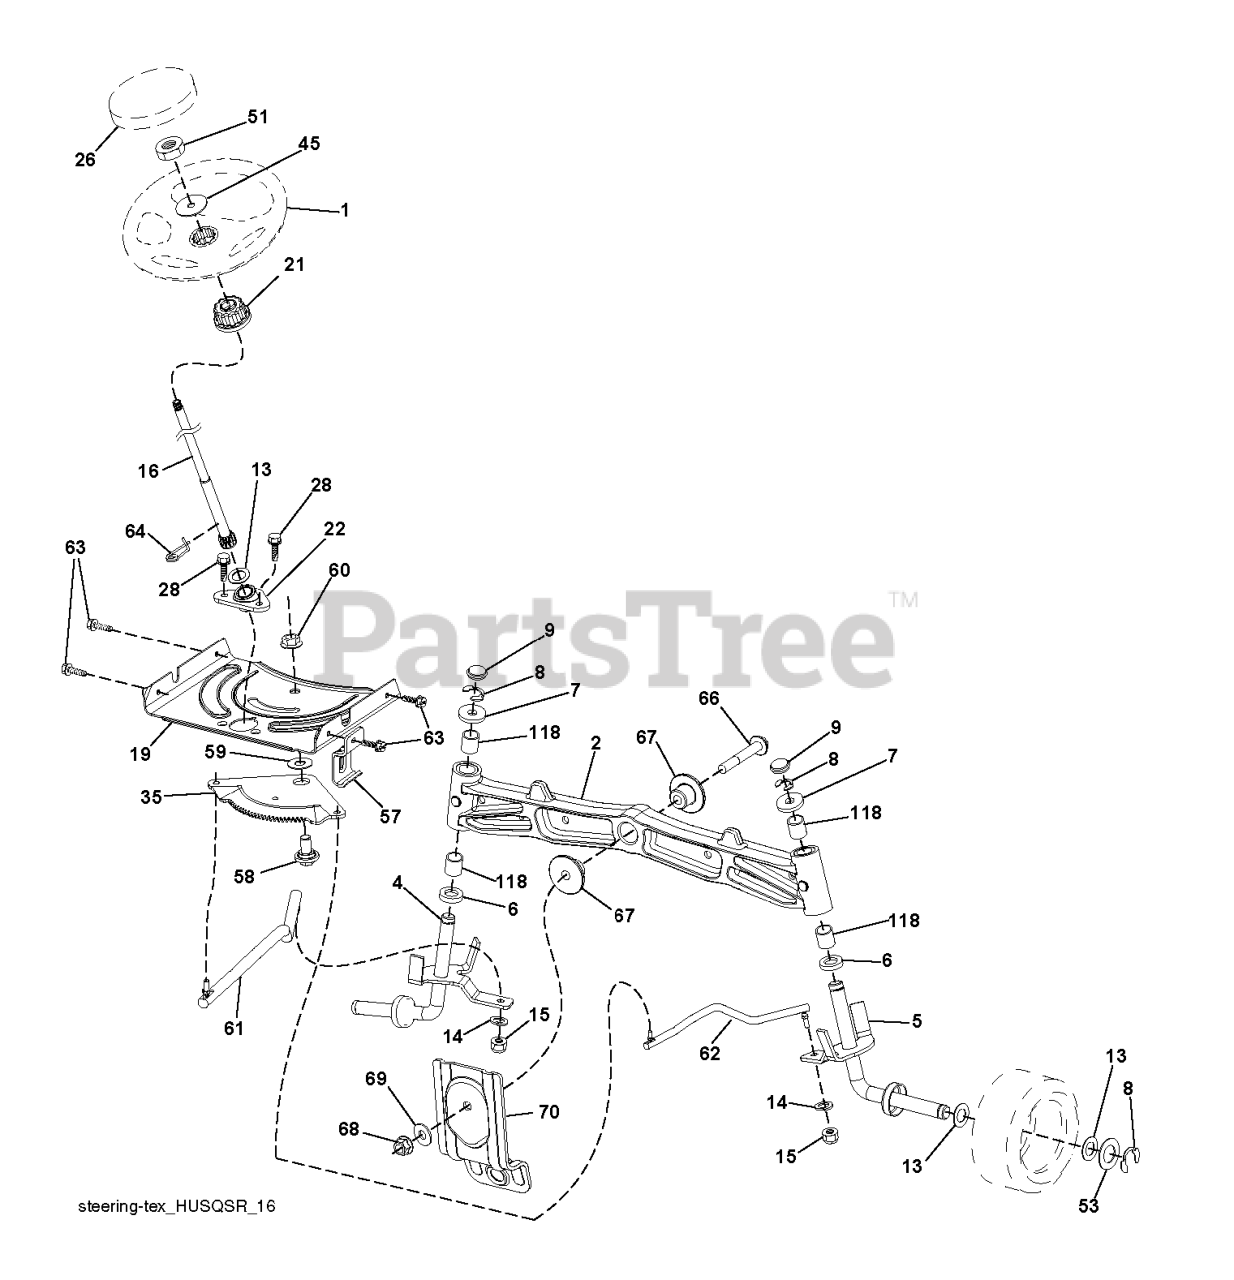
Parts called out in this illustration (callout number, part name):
1	RP WHEEL.STEER.HUSQ.PREM.OVMLD
2	AXLE.SVC.ASM CAST IRON.TEX
4	SPINDLE.WELDED.LH.16"TEX
5	SPINDLE.WELDED.RH.16"TEX
6	THRUST WASHER
9	CAP.SPINDLE.BLACK
14	WASHER, LOCK 3/8
15	NUT CROWNLOCK 3/8-24
16	SHAFT.STEER.STEALTH.DD
19	PLATE.STEER.DDL.NLT/NG
21	ADAPTER, WHEEL STNG..
22	STEERING.SUPT.LOWER.
26	RP INSERT.CAP.WHL.STRG.HUSQ.
28	SCREW, 3/8-16X3/4
35	GEAR.SECTOR.PLATE.DDL.
45	WASHER 9/16"ID, 2 3/8"OD
51	NUT.HEX.1/2-20
53	WASHER.HARDENED
57	BRKT.UPSTOP.GT/LT.TEX
58	BOLT.SHOULDER.SECTOR.P
59	WASHER.THURST.SECTOR.S
60	NUT FLANGE LOCK 5/8-11
61	DRAGLINK.LH.BALLSTUD.D
62	DRAGLINK.RH.BALLSTUD.D
63	SCREW
64	RETAINER.CLIP.SPRING.S
66	BOLT HEX FGHD 7/16-14 X 3 SERR
67	BUSHING.PM.FRONT AXLE
68	NUT.LOCK.FLANGE.7/16
69	WASHER.1.5X.505X.118
70	BRKT.DECK.SUSPENSION.F
118	BUSHING, AXLE CAST
